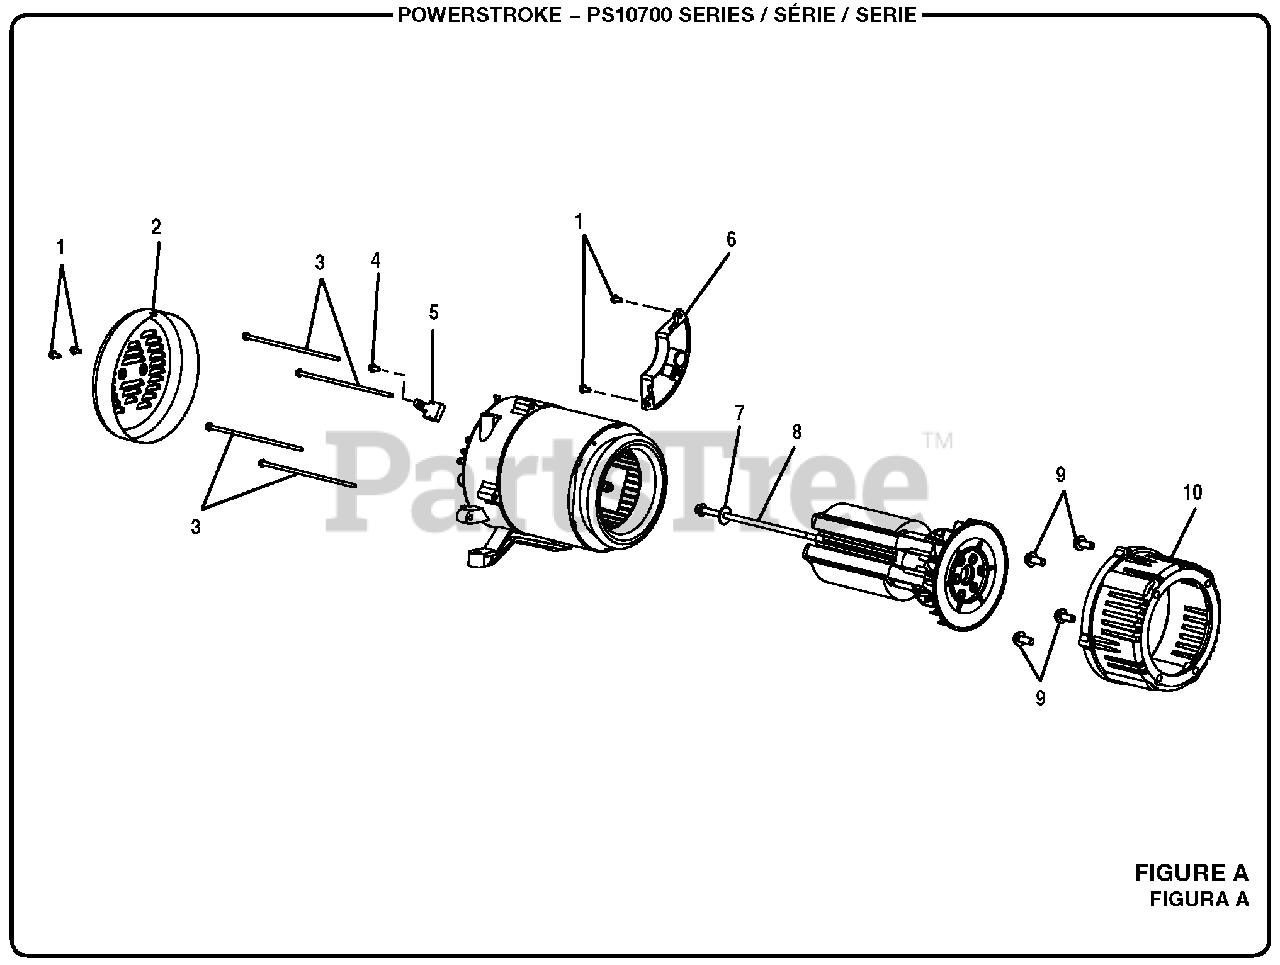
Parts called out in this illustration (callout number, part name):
2	Brush Cover
3	Bolt (1/4-20 x 6 in.)
4	Bolt (Brush Assembly)
5	Brush Assembly
6	Automatic Voltage Regulator
7	Lock Washer (5/16 in.)
8	Bolt (5/16-24 x 9-1/2 in., Hex. Hd.)
9	Bolt (3/8-18 x 1-1/4 in.)
10	Engine Adapter
